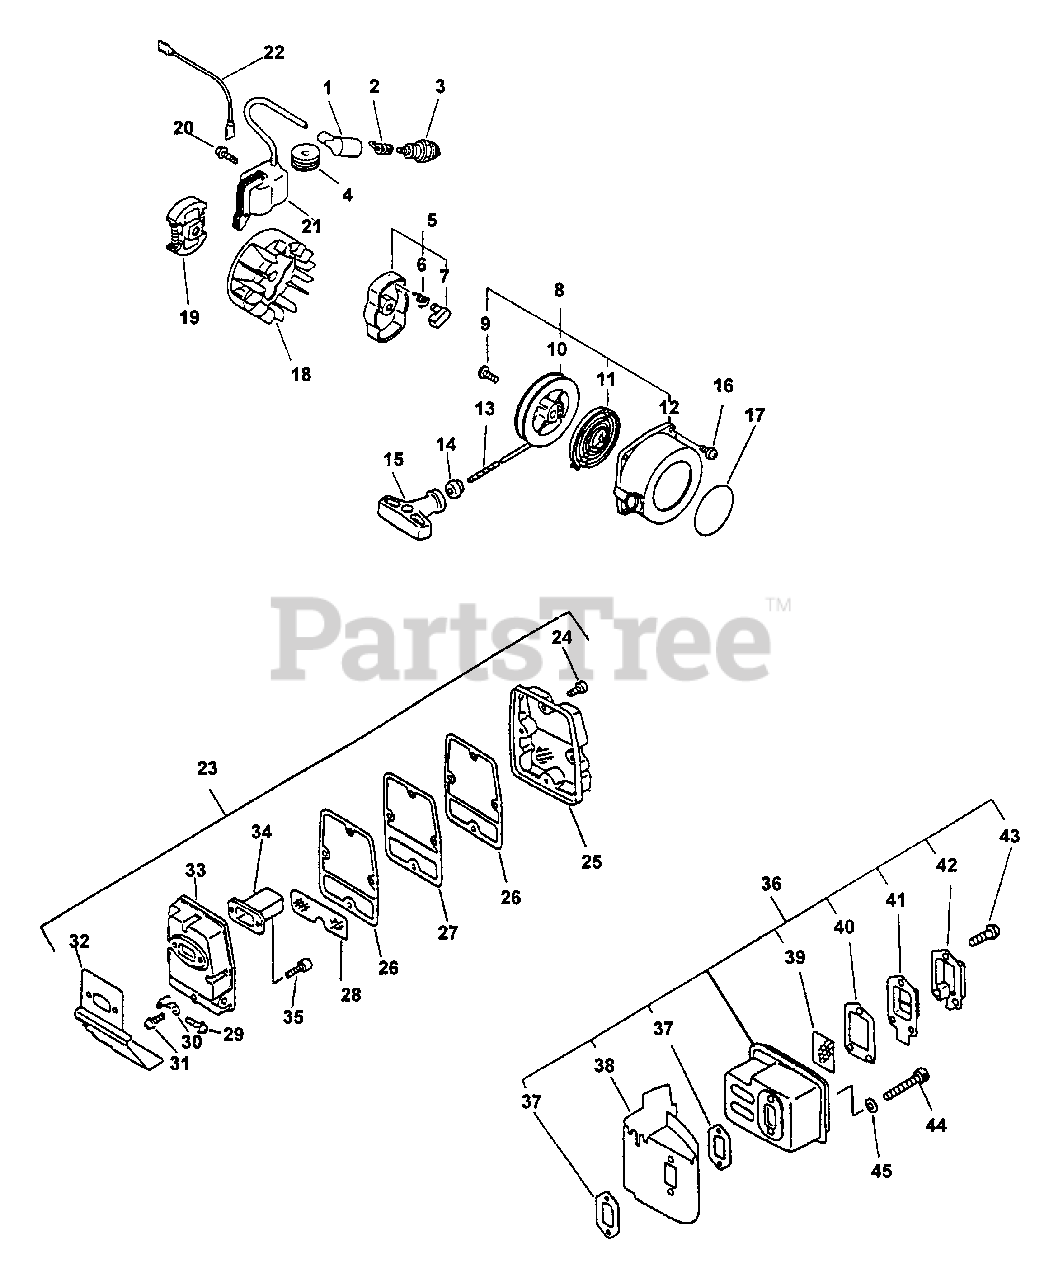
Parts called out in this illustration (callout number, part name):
1	CAP, SPARK PLUG
2	TERMINAL, SPARK PLUG
3	SPARK PLUG - BPM-7Y
5	PAWL ASSY, STARTER
6	SPRING, RETURN
7	PAWL, STARTER - BLACK
8	STARTER ASSY
9	SCREW
10	REEL, ROPE
11	SPRING, RECOIL
12	CASE, RECOIL STARTER
13	BOLT 4×16
14	LABEL, ECHO
15	ROPE, STARTER
16	GUIDE, ROPE
17	GRIP, STARTER
18	FLYWHEEL
19	CLUTCH ASSY
20	SCREW 4×22
21	COIL, IGNITION
22	LEAD
23	MUFFLER ASSY
24	SCREW 5×16
25	LID, MUFFLER
26	GASKET, EXHAUST
27	PLATE, MUFFLER
28	SCREEN, SPARK ARRESTER
29	SCREW 5×14
30	BRACKET, MUFFLER
31	SCREW 5×10
32	GASKET, MUFFLER
33	MUFFLER
34	BAFFLE, MUFFLER
35	BOLT M5×18
36	MUFFLER ASSY
37	GASKET, EXHAUST
38	COVER, EXHAUST
39	SCREEN, SPARK ARRESTER
40	GASKET, EXHAUST
41	GUIDE, EXHAUST
42	OUTLET, EXHAUST
43	SCREW 4×10
44	BOLT 5×55
45	WASHER, FLAT 5.5×10×0.8
